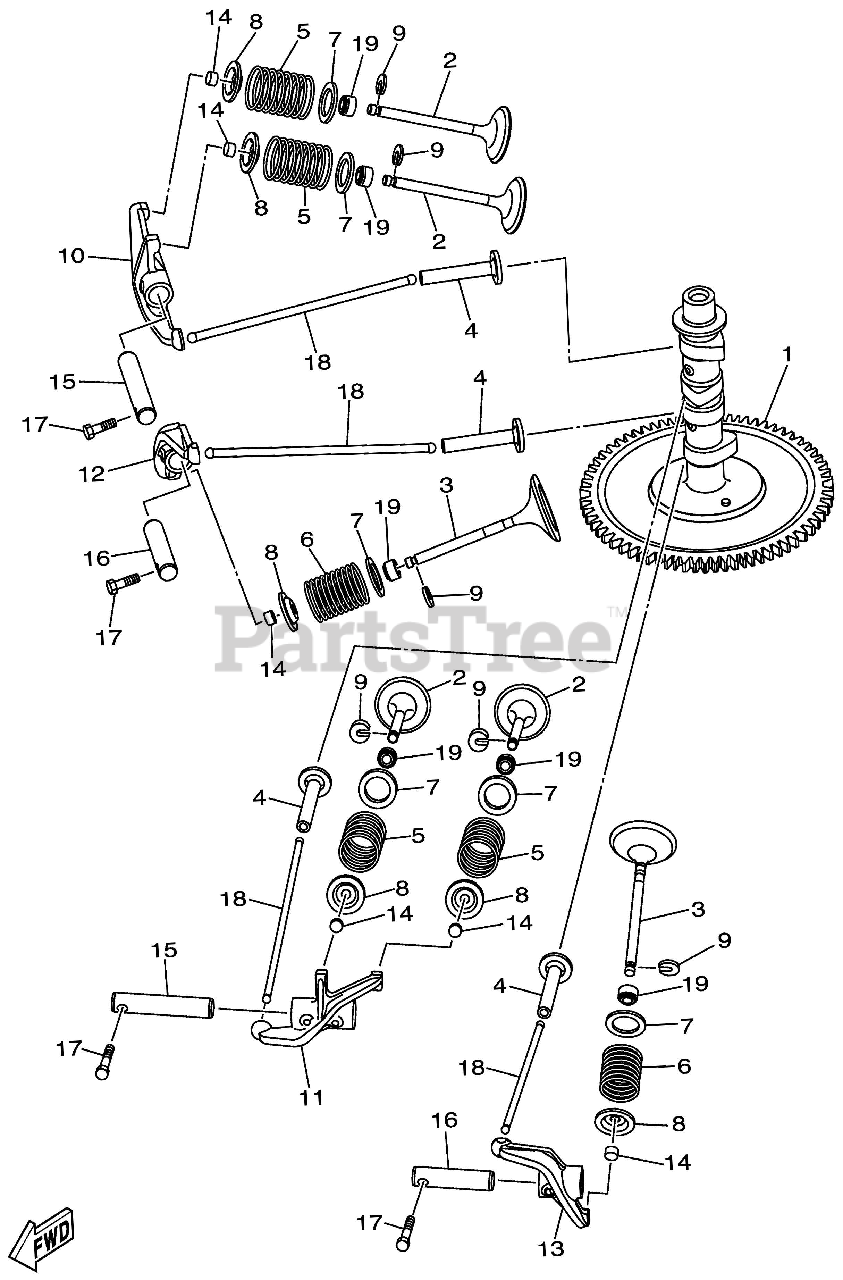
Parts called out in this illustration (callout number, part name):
1	CAMSHAFT ASSY 1
2	VALVE, INTAKE
3	VALVE, EXHAUST
4	LIFTER, VALVE
5	SPRING, COMPRESSION
6	SPRING, COMPRESSION
7	SEAT, VALVE SPRING
8	RETAINER, VALVE SPRING
9	LOCK, VALVE SPRING RETAINER
10	ARM, VALVE ROCKER
11	ARM, VALVE ROCKER 2
12	ARM, VALVE ROCKER 3
13	ARM, VALVE ROCKER 4
14	PAD, ADJUSTING 1.800
14	PAD, ADJUSTING 1.850
14	PAD, ADJUSTING 1.900
14	PAD, ADJUSTING 1.950
14	PAD, ADJUSTING 2.000
14	PAD, ADJUSTING 2.050
14	PAD, ADJUSTING 2.100
14	PAD, ADJUSTING 2.150
14	PAD, ADJUSTING 2.200
14	PAD, ADJUSTING 2.250
14	PAD, ADJUSTING 2.300
14	PAD, ADJUSTING 2.350
14	PAD, ADJUSTING 2.400
14	PAD, ADJUSTING 2.450
14	PAD, ADJUSTING 2.500
14	PAD, ADJUSTING 2.550
14	PAD, ADJUSTING 2.600
14	PAD, ADJUSTING 2.650
14	PAD, ADJUSTING 2.700
14	PAD, ADJUSTING 2.750
14	PAD, ADJUSTING 2.800
14	PAD, ADJUSTING 2.850
14	PAD, ADJUSTING 2.900
14	PAD, ADJUSTING 2.950
14	PAD, ADJUSTING 3.000
15	SHAFT, ROCKER
16	SHAFT, ROCKER 2
17	BOLT, HEXAGON
18	ROD, VALVE PUSH
19	SEAL, VALVE STEM
